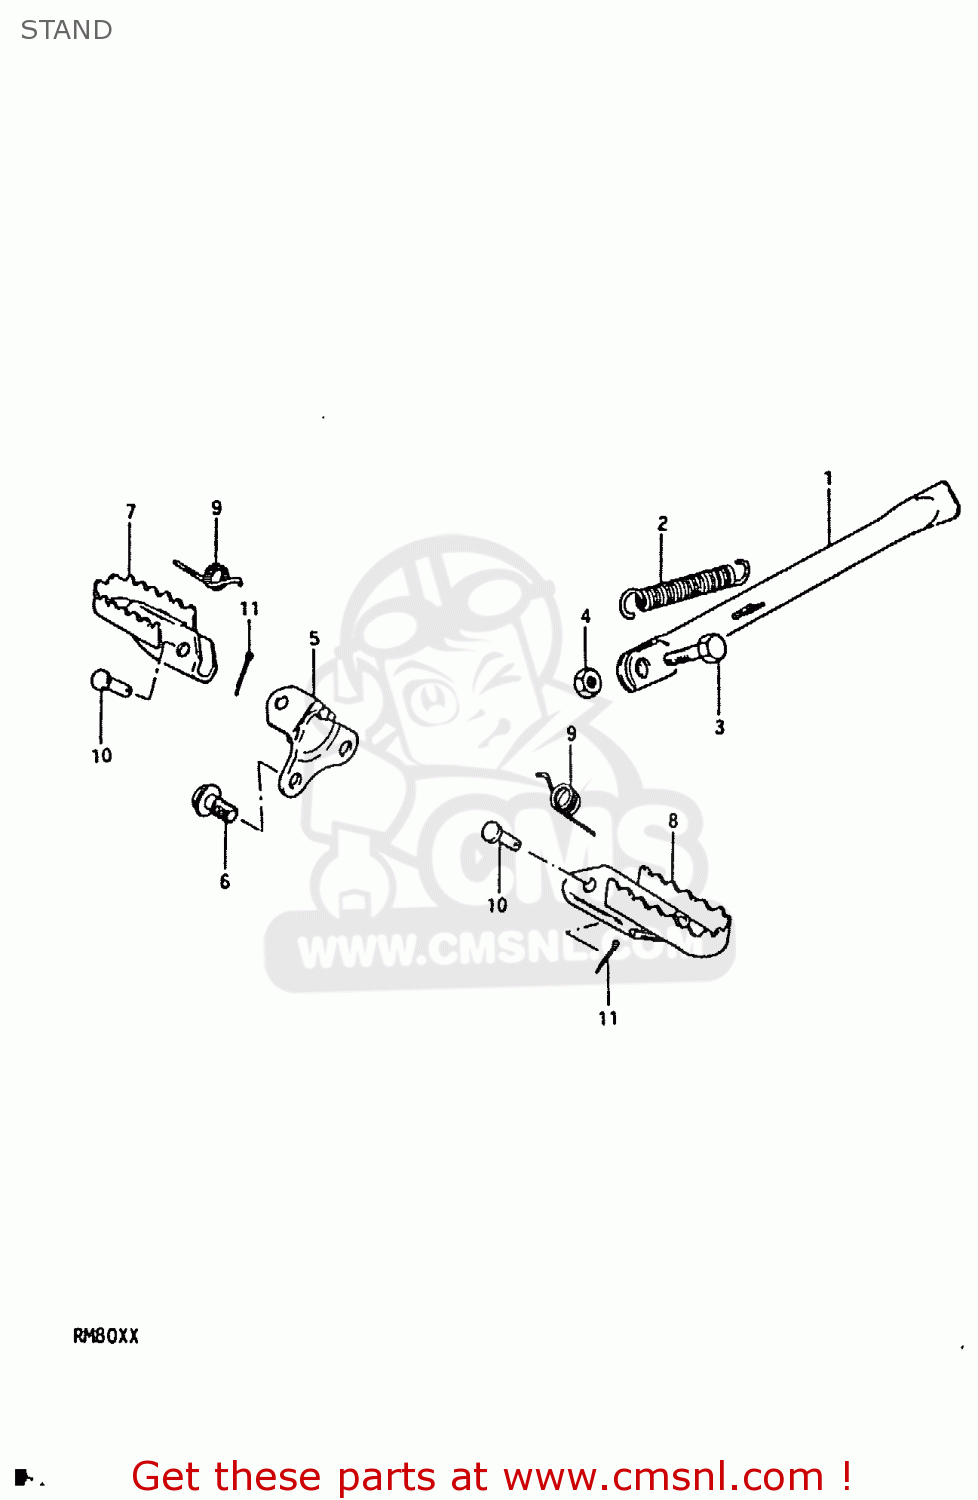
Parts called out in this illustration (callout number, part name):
1	STAND,SIDE
2	SPRING
3	BOLT
4	NUT
5	BAR,FRONT FOOTREST
6	BOLT(10X20)
7	FOOTREST,FRONT,RIGHT
8	FOOTREST
9	SPRING
10	PIN
11	PIN 20X20
